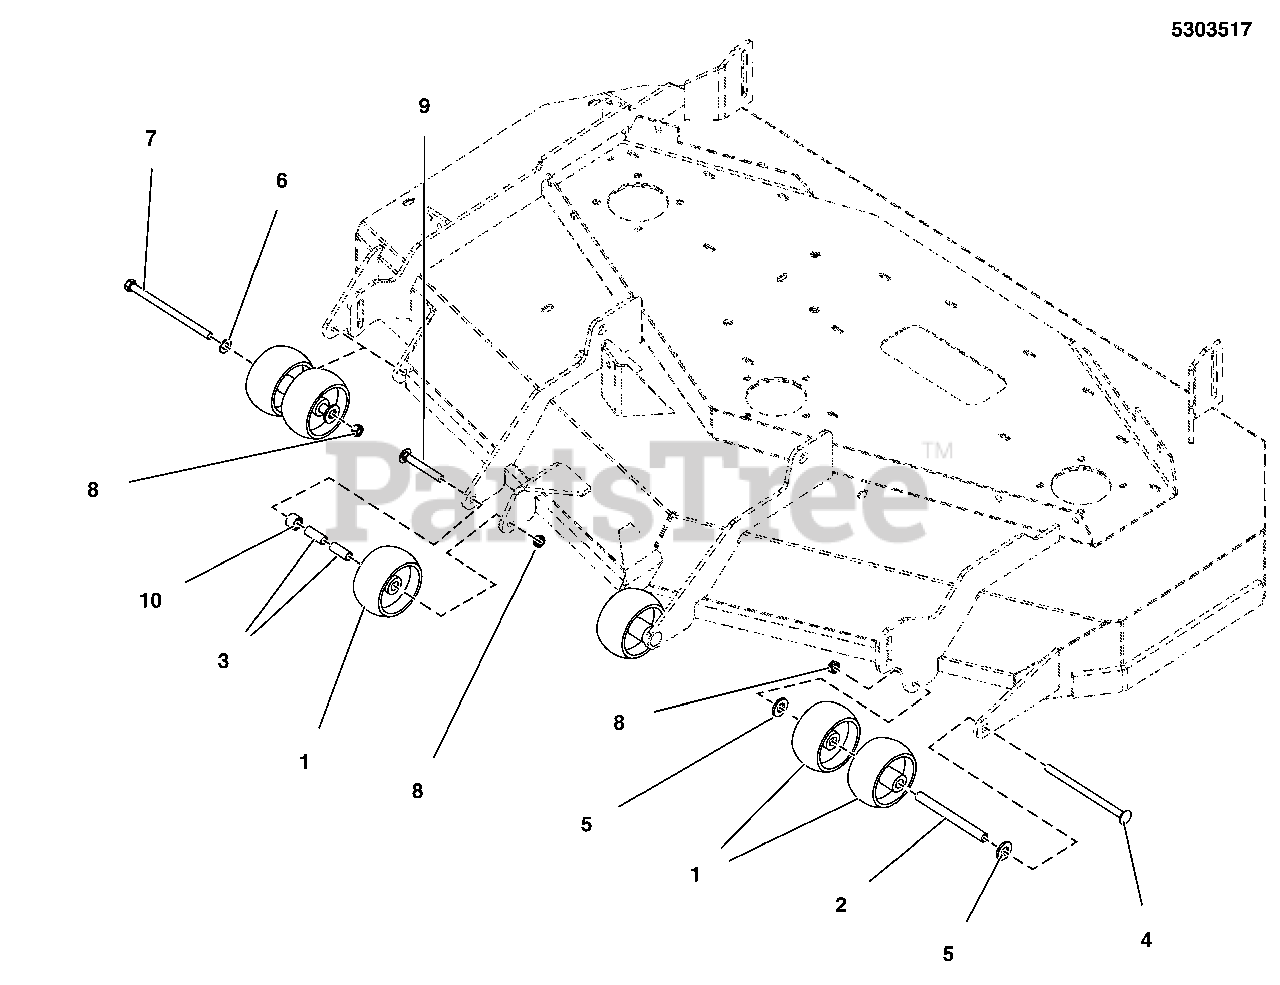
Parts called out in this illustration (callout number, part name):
1	GAUGE WHEEL
2	SPACER, .38 X .50 X 5.06
3	SPACER, .38 X .50 X 1.25
4	CARRIAGE BOLT, 3/8-16 X 6"
5	WASHER, 1/2" GD9 YZ
6	WASHER 3/8" SAE
7	BOLT, 3/8-16, GD5
8	NUT, 3/8-16 HEX SIDE LOCK
9	BOLT, 3/8-16 X 3-1/2, CARRIAGE, GD5, CZ
10	SPACER, .51 X .75 X .56, CZ
